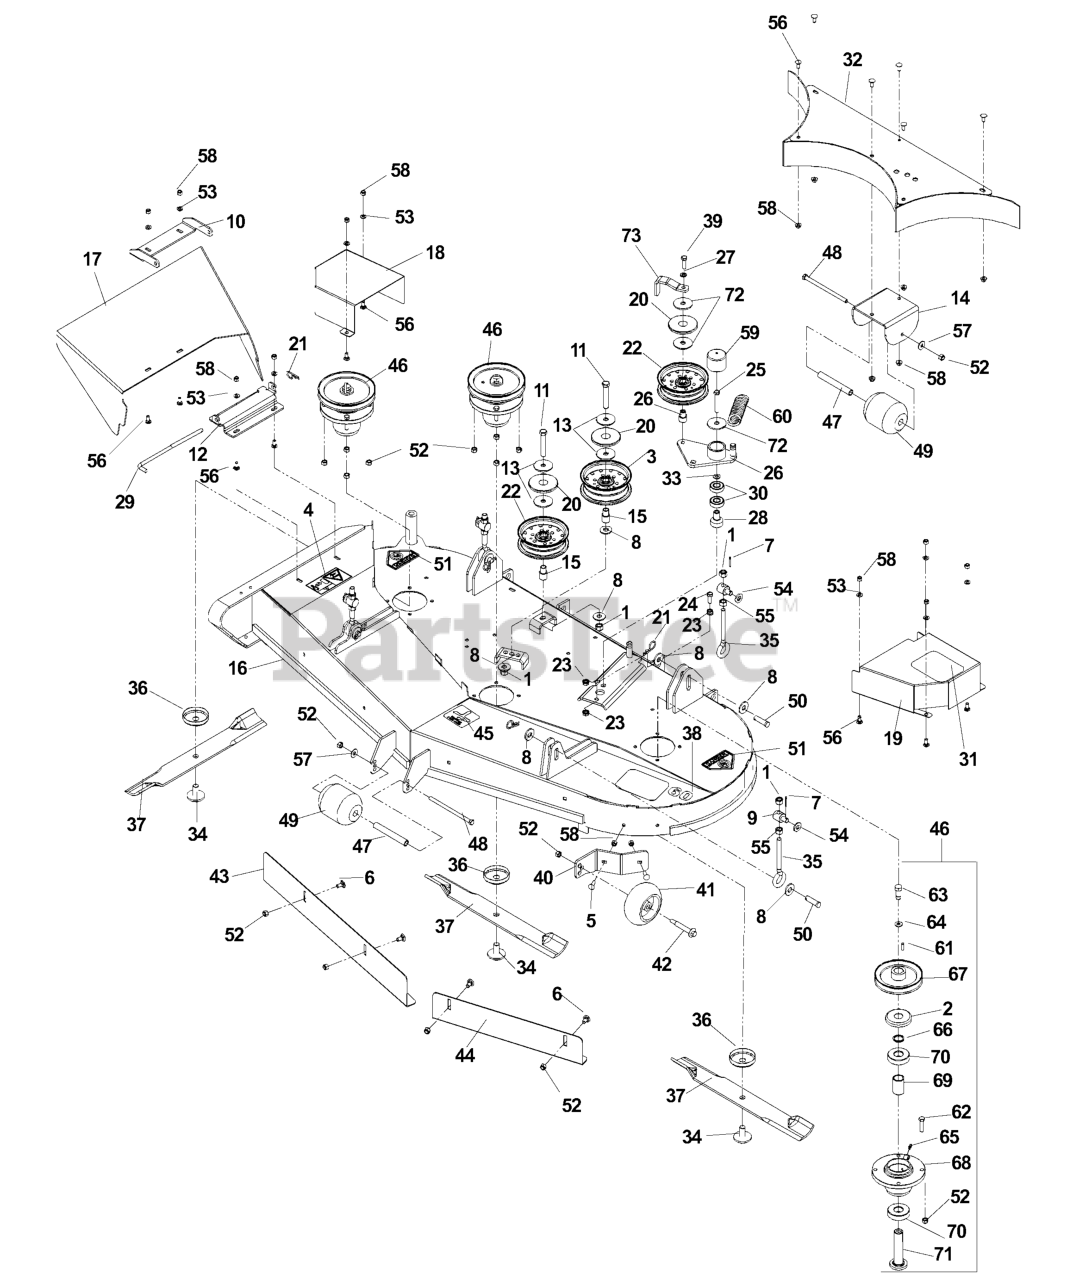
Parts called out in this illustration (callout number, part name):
1	NUT 1/2-13 HEX NYLOC ZD
2	TRASH GUARD
3	IDLER PULLEY (TALL)
4	DECAL, EURO SEVERING
5	RHSSNB 5/16C X 1.0
6	RHSNB 3/8-16 X 3/4 GR5 ZD
7	PIN COTTER 1/8 X 1 ZD
8	WASH USS FLAT 1/2
10	HINGE, DISCHARGE CHUTE, BLUE
11	SCREW, 1/2C X 3 HEX CAP
12	SUPT - CHUTE HINGE PAINTED
13	ISOLATOR WASHER
14	REAR CENTER ROLLER BKT 60 BLK
15	SPACER - IDLER
16	DECK W/DECAL 60" KODIAK
17	CHUTE - 60" PAINTED
18	PULLEY GUARD RH 60 PAINTED
19	PULLEY GUARD LH 60 PAINTED
20	TOP DUST CAP
21	PIN, COTTER 1 3/4
22	IDLER PULLEY
23	NUT 3/8C WHIZ
24	HCS 3/8C X 1
25	HCS 3/8C X 2 1/2
26	ARM, IDLER - WELDMENT
27	SLW 3/8 STD
28	BEARING PIVOT SPACER
29	DEFLECTOR PIN
30	BEARING, BALL
31	REAR FLOOR PAD-LH
32	W-BAFFLE WLDT.
33	WASHER 3/8 SAE FLAT
34	BLADE BOLT/WASHER
35	BOLT, EYE
36	TRASH GUARD
37	BLD 60" HI LIFT FUSION
38	DECAL, DECK 60"
39	HCS 3/8C X 1 1/4 GR5
40	BRACKET
41	GUAGE WHEEL
42	SHOULDER BOLT
43	BLOW BY BAFFLE
44	BLOW BY BAFFLE LH 60
45	DECAL, BELT ROUTING (18656)
46	SPINDLE ASSEMBLY
47	BUSHING
48	3/8-16 X 6-1/2 HHB GR8
49	ROLLER 3-3/4 DIA. X 4-1
50	CLEVIS PIN 1/2X1-3/4LG
51	DECAL, CPSC
52	NUT 3/8-16 NYLOC
53	FLAT WASHER 5/16 SAE
54	WASHER 1/2" FLAT
55	NUT HEX 1/2
56	BOLT 5/16C X 3/4" CARRIAGE
57	WASHER 3/8 FLAT
58	NUT 5/16 NYLOC
59	CAP, VINYL
60	DECK SPRING
61	KEY - 1/4 X .88
62	HCS 3/8C X 1 1/2
63	1/2-20 UNF X 1 1/4 HHBLT
64	WASHER .525 X 1.375 X .25
65	ZERK, 3/16, DRIVE IN
66	SPACER .25
67	PULLEY 6.45 METRIC
68	DECK HUB MACHINED
70	BEARING - 6305 - 2RS
71	SHAFT SHORT
72	WASHER, 3/8 SPEC
73	GUIDE, BELT
